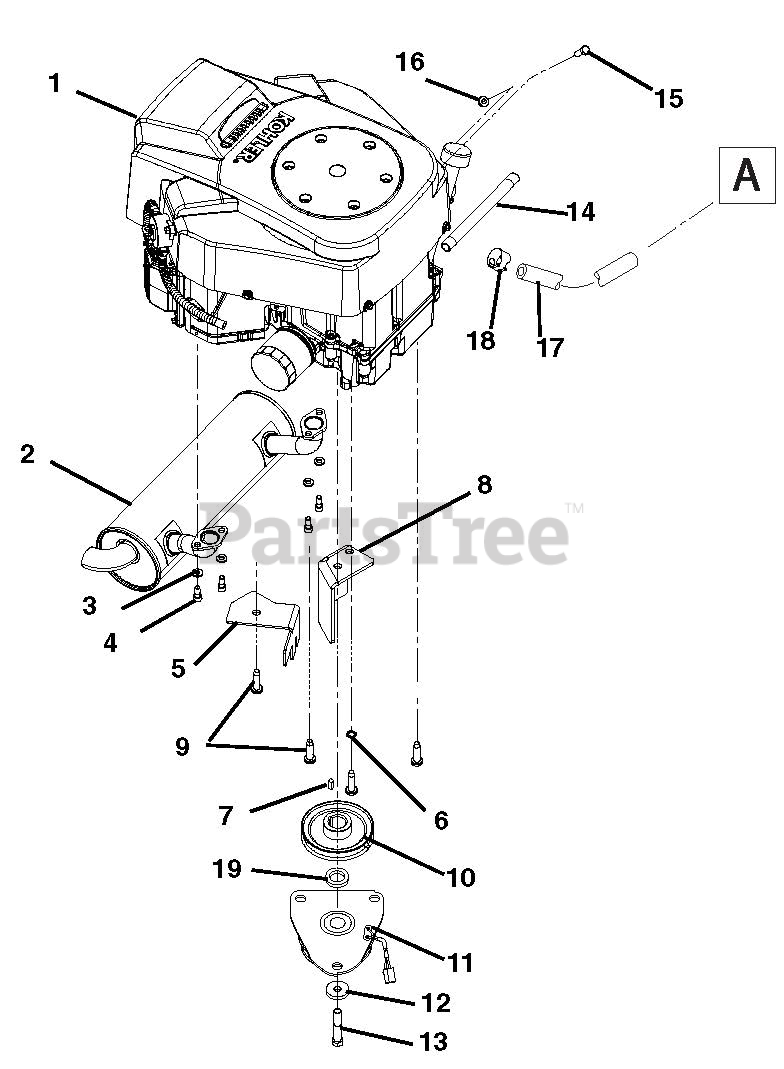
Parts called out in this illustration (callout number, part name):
1	Engine, Kohler Courage
1	Engine, 25HP Kohler Courage-Pro
1	Engine, 27HP Kohler Courage-Pro
1	Engine, 23HP Kohler Courage
2	Muffler, Kohler Engine
3	Washer, Locking .31 x .078 Reg
4	Screw, Cap .31-18 x .75 Socket Head
5	Guard, Clutch Wire
6	Washer, Locking-EXT.391 x .682 x .036
7	Key, Square .25 x .625 x .25 SAE 8630 OR SAE 1035
8	Anchor, Ogura Clutch
9	Screw, Tapping Hex Washer Head .38-16 x 1.50
10	Sheave, 4.831 x 1.002 Engine
11	Clutch Assembly, OGURA
12	Washer, Flat-Steel .469 x 2.00 x .25
13	Bolt, Hex .44-20 x 2.50 Grade 5
14	Hose, Hydraulic .38-11-0K M6N0-F6J0
15	Bolt, Hex .31-18 x 1.00 Grade 5
16	Nut, .31-18 Nyloc Flange
17	Hose, Gas Line Low Perm
18	Clamp, Fuel Line
19	Spacer, 1.002ID x 1.75 OD x .266
